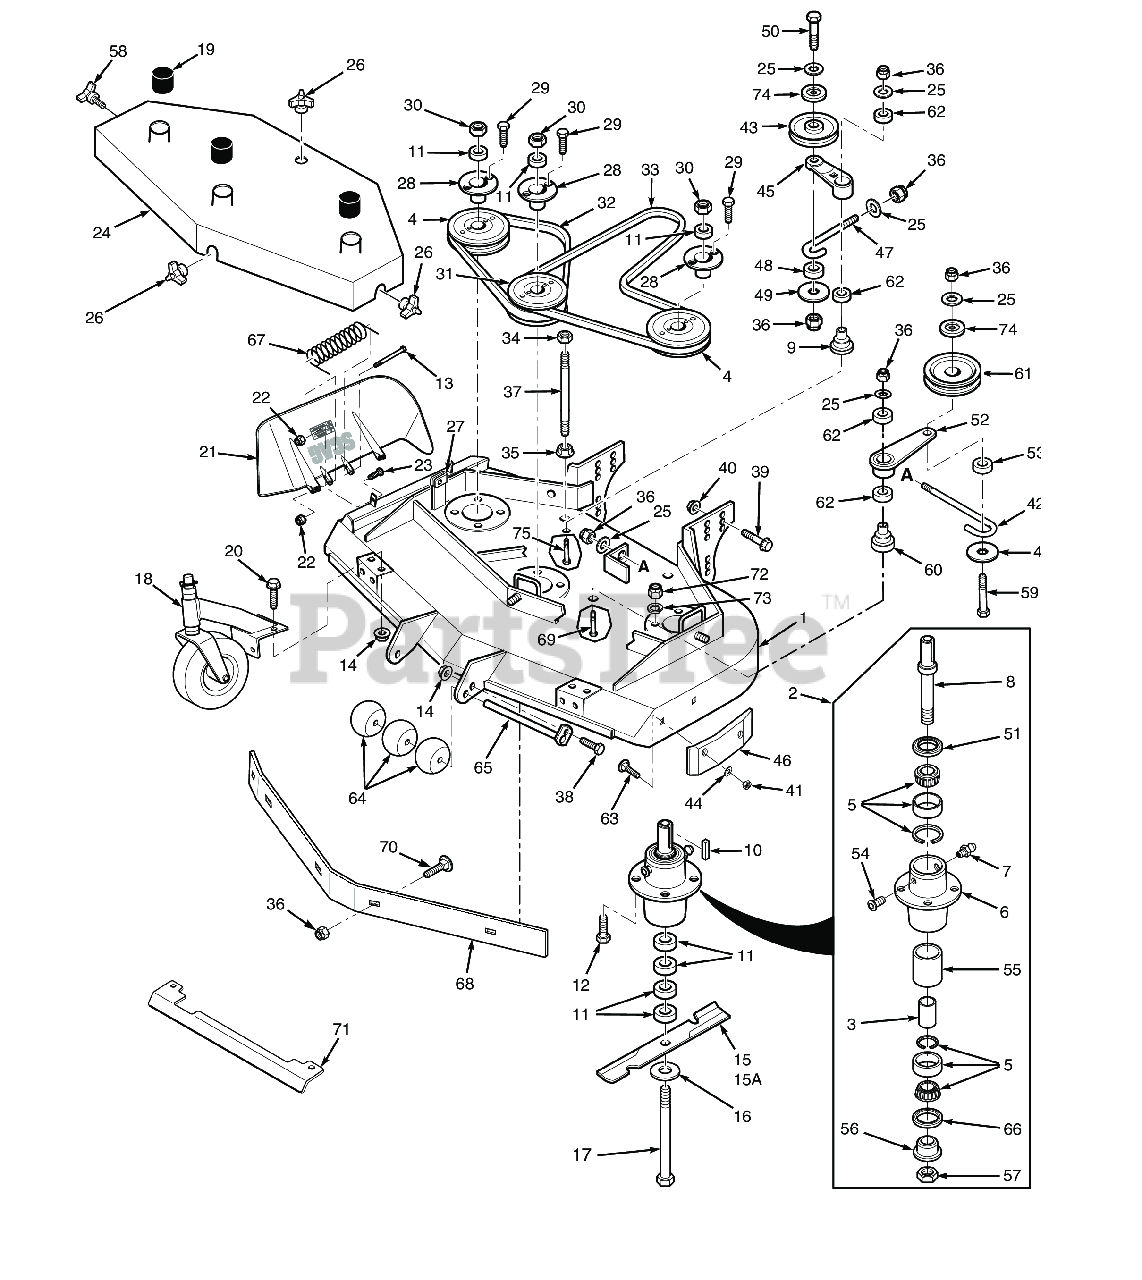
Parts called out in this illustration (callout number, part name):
1	Cutter Deck w/Decals
2	Cutter Spindle Assembly
3	SLEEVE, CUTTER SPINDLE
4	Pulley, 5.75 O.D. (Gasoline Engines)
5	Tapered Bearing Set (Two Bearings W/Race)
6	Housing, Spindle
7	GREASE FITTING, STR. 1/4-28 SELF TAP.
8	Spindle Shaft, Tapered Brng
9	Idler Pivot
10	Key, 1/4 x 1/4 x 2.0"
11	Spacer, Cutter Blade - Small
12	Bolt, Hex Head 5/16-18 x 1-1/2" Grade 8
13	Bolt, 5/16-18 x 4-3/4" Hex Head
14	Nut, Serrated Flange 5/16-18 (Right Front Engine Mounting, Briggs and Kohler Only)
15	Cutter Blade 16-1/2" (marbane)
15A	Cutter Blade 16-1/2" Hi Lift (marbane)
16	Flatwasher, 5/8-.688 x 1-3/4 x .134 HD
17	BOLT, HEX HEAD, 5/8-11 X 9-1/2 GR.5
18	Caster Assembly
20	Capscrew, 5/16-18 x .75 Serrated Flange Hex Head
21	Discharge Chute Assembly - 48V
22	HEX NUT, ELASTIC STOP LOCK, 5/16-18
23	Bolt, Hex Head 5/16-18 x 1-1/2" (Right Front Engine Mounting, Briggs and Kohler Only)
24	Belt Cover (Incl. decals)
25	Flatwasher, 3/8 (.391 x .938 x .105 HD) Grade 8
26	WINGNUT, PLASTIC 3/8-16 X .875
27	U-Nut, 3/8-16 (short)
28	Hub, Tapered 1-1/8" Bore
29	Bolt, Hex Head 1/4-20 x 1" Grade 8 Black
30	Hex Locknut, Elastic Stop, 3/8-16
31	PULLEY, DOUBLE GROOVE, 5.75 O.D.
32	Belt, RH Blade Drive 48"
33	BELT, BLADE DRIVE
34	Bolt, Hex Head 3/8-16 x 1" Ser. Flg.
35	NUT, 3/8-16 SERRATED FLANGE HEX HEAD
36	HEX NUT, ELASTIC STOP LOCK, 3/8-16
37	Bolt, 5/16-18 x 1" Hex Head
38	Bolt, Heax Head 5/16-18 x 1" (48V / 52V)
39	Serr. Fl. Hex Head Capscrew, 1/2-13 x 1-3/4
40	Nut, Elastic Stop 1/2-13, (STT-52 & STTII-52)
41	Nut, Center Lock, 5/16-18(32)
42	J-Hook, Idler Pulley
43	IDLER PULLEY, "V" GROOVE
44	Flatwasher, 5/16-.344 x .688 x .065 (48V / 52V)
45	Idler Arm Assembly
46	Pad, Deck Wear
47	J-HOOK, IDLER PULLEY
48	SPACER, J PULL ROD
49	Flatwasher, 3/8 (.375 x 1-1/2" x 16 ga.)
50	Capscrew, Hex Head 3/8-16 x 2-1/2"
51	SEAL, 2.00 O.D. X 1.50 BORE
52	Idler Arm Assy.
53	SPACER, J-PULL ROD
54	RELIEF FITTING, TAPERED BEARING SPINDLE
55	Spacer, Outside, Cutter Spindle
56	SPINDLE BUSHING, BOTTOM
57	Nut , Spec ial 1 -1/ 1 6 - 1 8
58	Knob, w/stud 3/8-16 x 1-1/4"
59	Capscrew, Hex Head 3/8-16 x 3-3/4"
60	Pivot, Idler - Short
61	Idler Pulley, Belt Clutch
62	BEARINGS, BALL, NEUTRAL RETURN
63	Bolt, 5/16-18 x .75 RHSN Carriage
64	Wheel, Anti-Scalp
65	Shaft Weldment, Guide Roller
66	Seal, 2.00" O.D. x 1.625" Bore
67	Spring, Discharge Chute
68	Baffle Custom-Cut, 48V (7-Position)
69	Capscrew, Hex Head 3/8-16 x 3.25"
70	Carriage Bolt, 3/8-16 x 1.0"
71	Heatshield, 16" Small Frame
72	Lock Nut, 5/16-18 Elastic Stop Grade 8
73	Lockwasher, 5/16 (.317 x .586 x .078) Helical Spring
74	Quick Pin, 5/16" Dia.
75	Capscrew, Hex Head 3/8-16 x 2.75"
